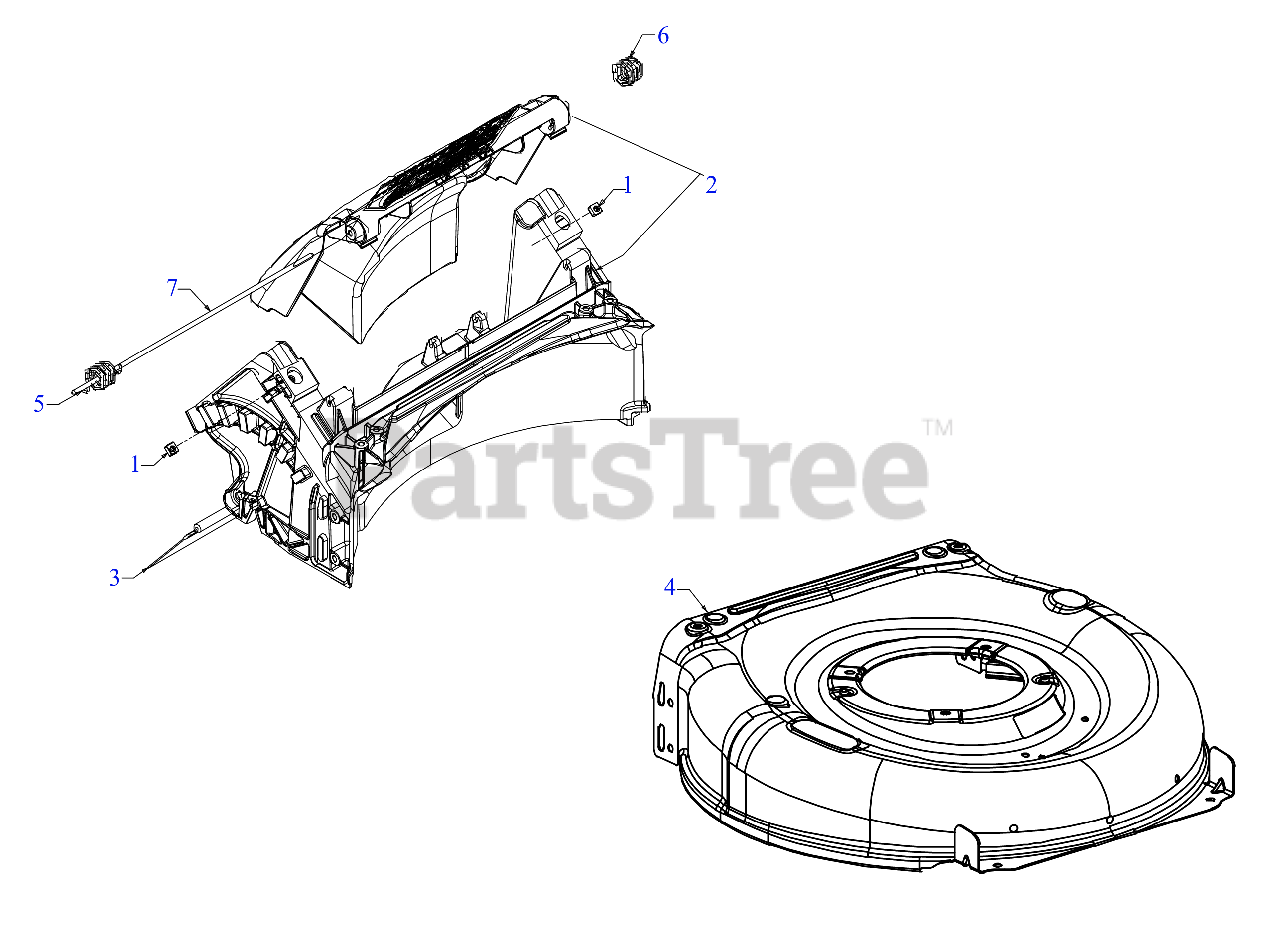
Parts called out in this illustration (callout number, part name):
1	SQUARE NUT 1/4-20
2	REAR BAG DOOR ASSEMBLY
3	TRAILSHIELD
5	TORSION SPRING (RH)
6	TORSION SPRING (LH)
7	REAR DOOR PIVOT ROD
